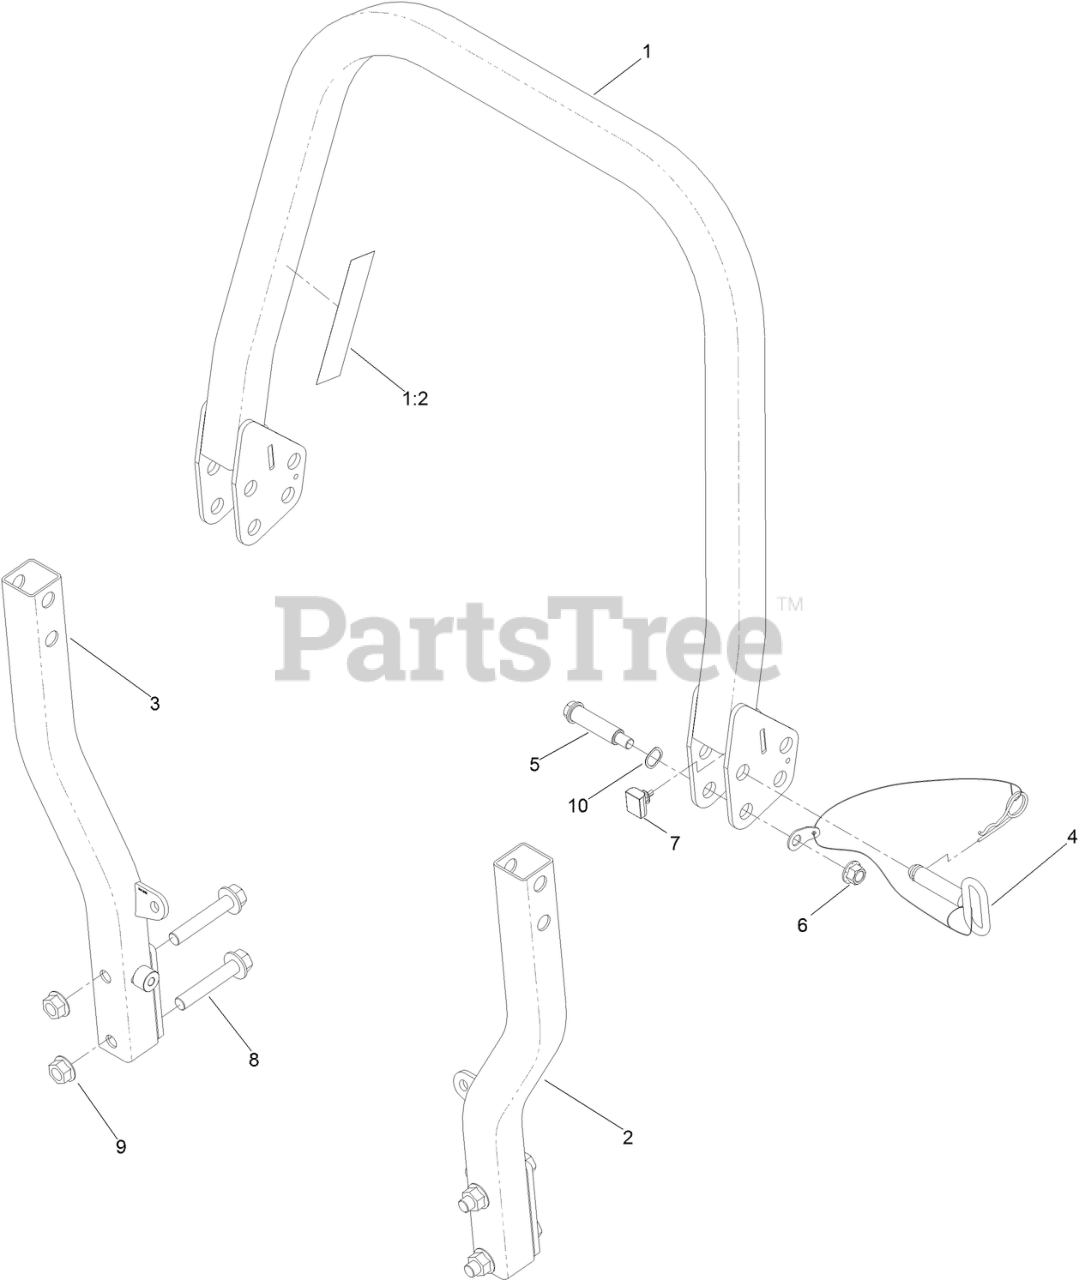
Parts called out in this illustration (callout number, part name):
1	UPPER ROPS ASM
1:2	DECAL-WARNING
2	LH LOWER ROPS ASM
3	RH LOWER ROPS ASM
4	PIN-FOLD, ROPS
5	BOLT-SHOULDER
6	NUT-LOCK
7	BUMPER-ROPS
8	SCREW-HHF
9	NUT-FLANGE
10	WASHER-WAVE
